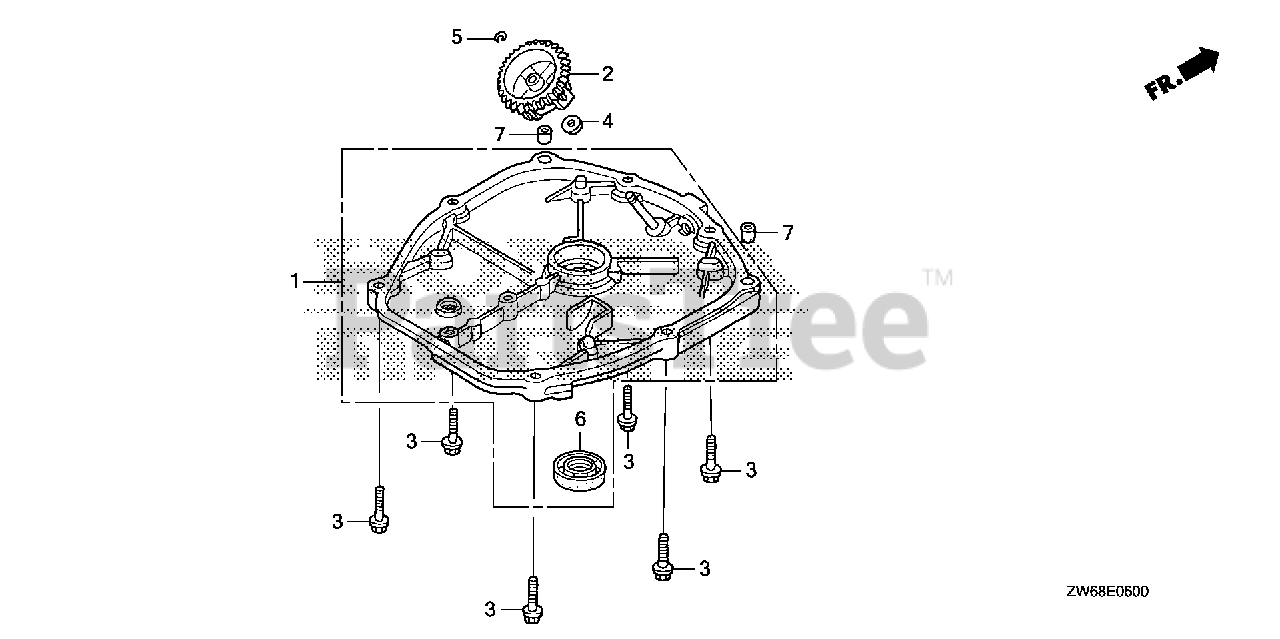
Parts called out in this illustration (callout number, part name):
1	COVER, CRANKCASE SIDE
2	HOLDER, GOVERNOR WEIGHT
3	BOLT, FLANGE (5X23) (CT200)
4	WASHER (4.2X13)
5	CLIP, GOVERNOR HOLDER
6	OIL SEAL (17X27X5) (KOYO)
7	PIN, DOWEL (6X10)
